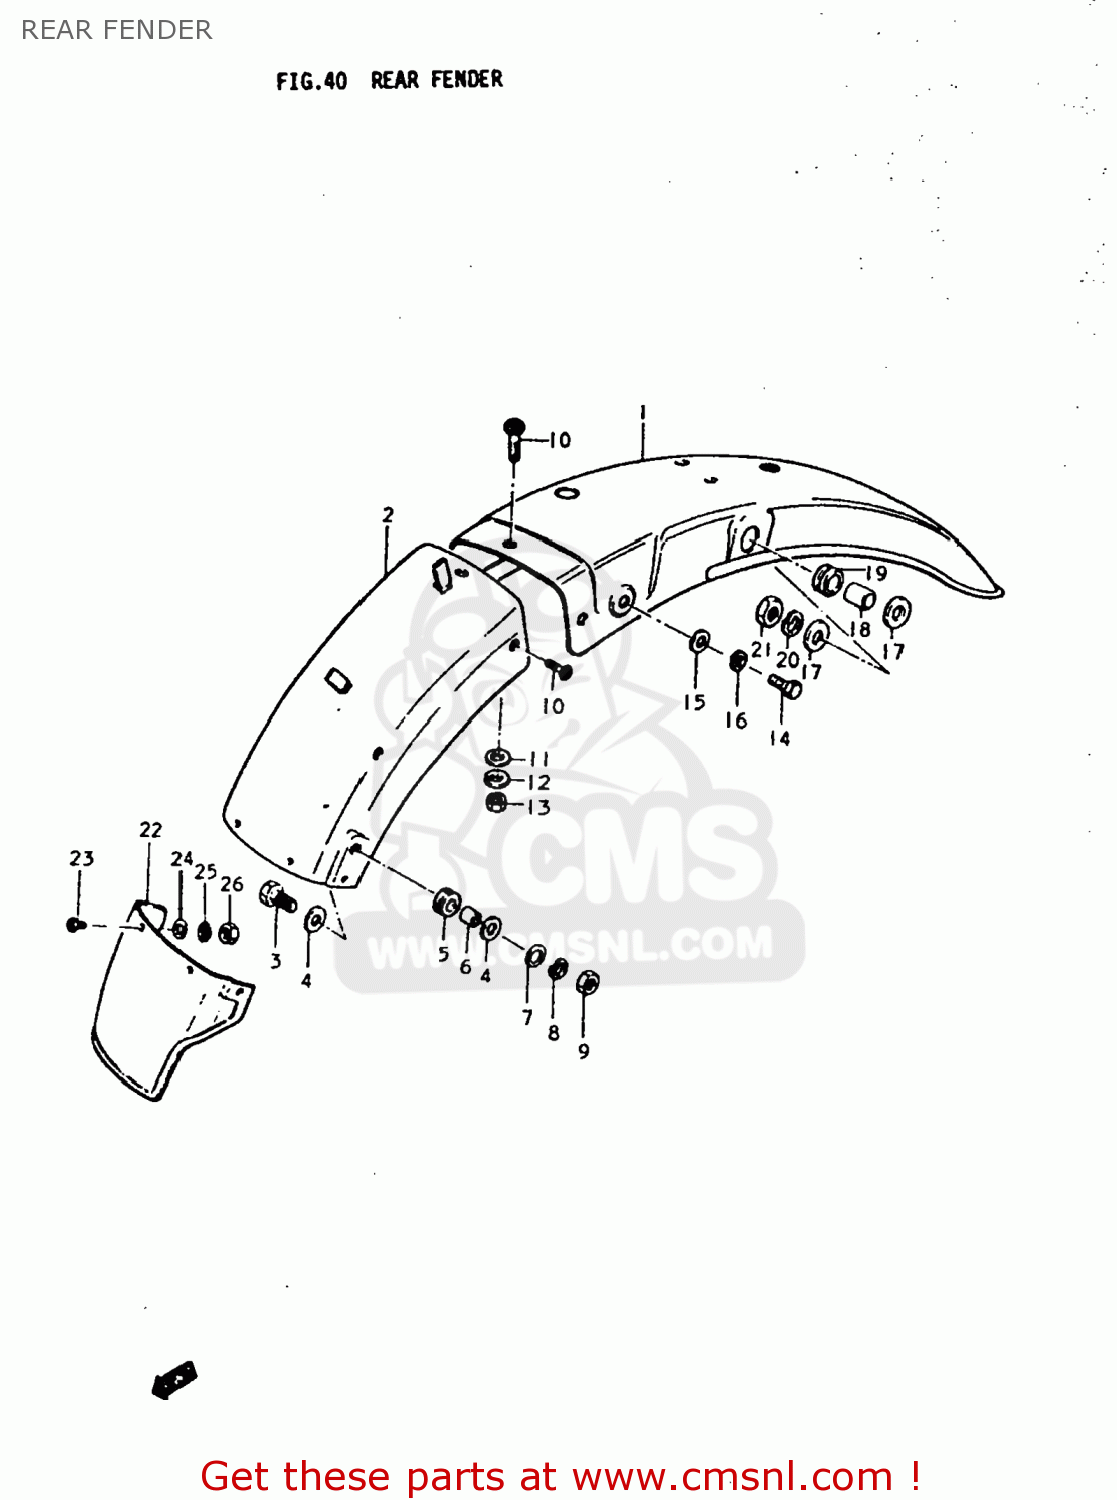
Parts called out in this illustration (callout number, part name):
1	FENDER,REAR
2	FENDER,REAR
3	BOLT
4	WASHER (6.5X20X1.2)
5	CUSHION
6	SPACER(6.1X9X7.5)
7	WASHER
8	LOCK WASHER
9	NUT
10	SCREW
11	WASHER
12	LOCK WASHER
13	NUT
14	BOLT
15	WASHER
16	LOCK WASHER
17	WASHER(10.3X25X1.5
18	SPACER
19	CUSHION
20	LOCK WASHER
21	NUT
22	MUD GUARD,REAR FENDER
23	SCREW
24	WASHER(5.2X16X1)
25	LOCK WASHER
26	NUT
